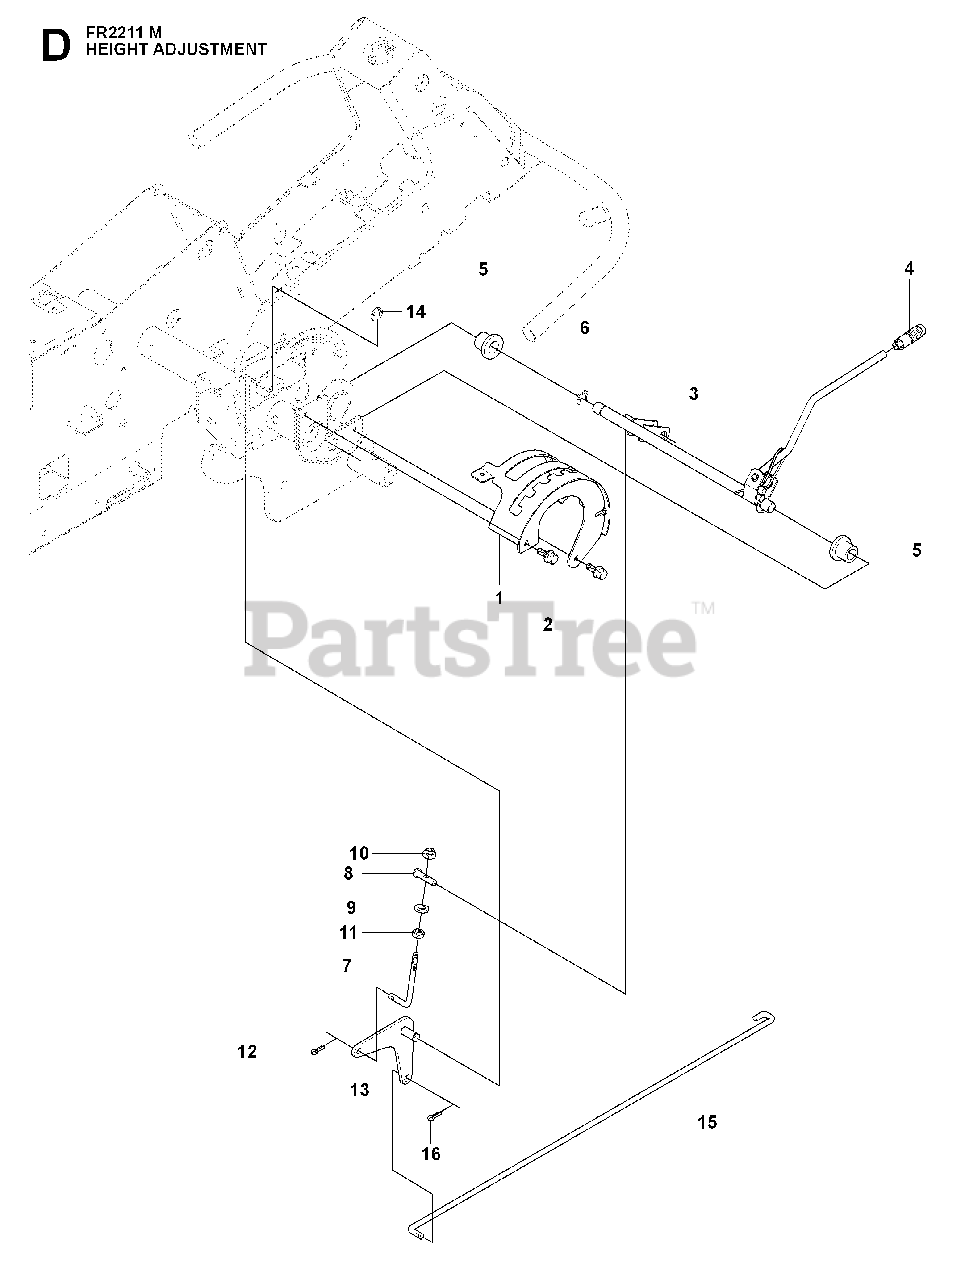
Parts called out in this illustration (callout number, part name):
4	GEAR STICK KNOB
5	BUSHING
9	WASHER
10	LOCKNUT M8
11	NUT
12	SPLIT PIN
14	RETAINING RING
16	SPLIT PIN
